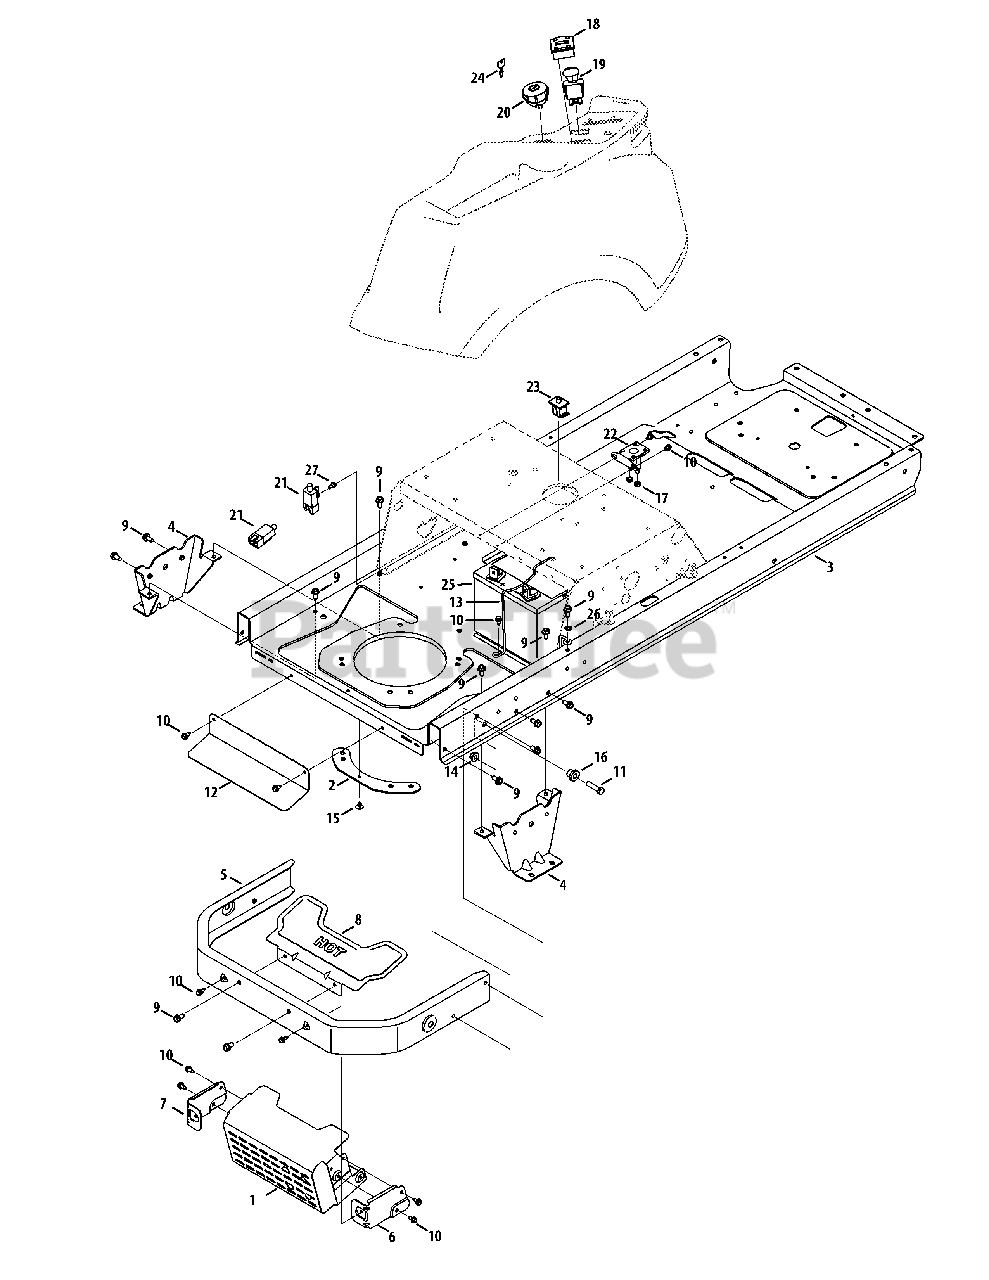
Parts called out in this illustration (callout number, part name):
1	Muffler Shield Assembly
3	Frame Assembly
4	Transmission Mounting Bracket
5	Rear Bumper
6	Muffler Mounting Shield Bracket, RH
7	Muffler Mounting Shield Bracket, LH
8	Muffler Shield
9	Hex Washer Screw 5/16-18 x .750
10	Hex Washer Screw 1/4-20 x .625
11	Hex Screw 3/8-16 x 1.25
12	Lower Heat Shield
13	Battery Rod
14	Flange Lock Nut, 3/8-16
15	Clip .250 Dia. x .500 LG
16	Shoulder Spacer .38 x 1.0 x .70
17	Flange Lock Nut 1/4-20
18	Hour Meter/Service Minder
19	Electric PTO Switch
20	Key Switch
21	Interlock Switch
22	Solenoid
23	Seat Switch
24	Key, Assembly
25	Battery
26	Lock Washer 5/16
27	Shoulder Screw #10-32 x .500
